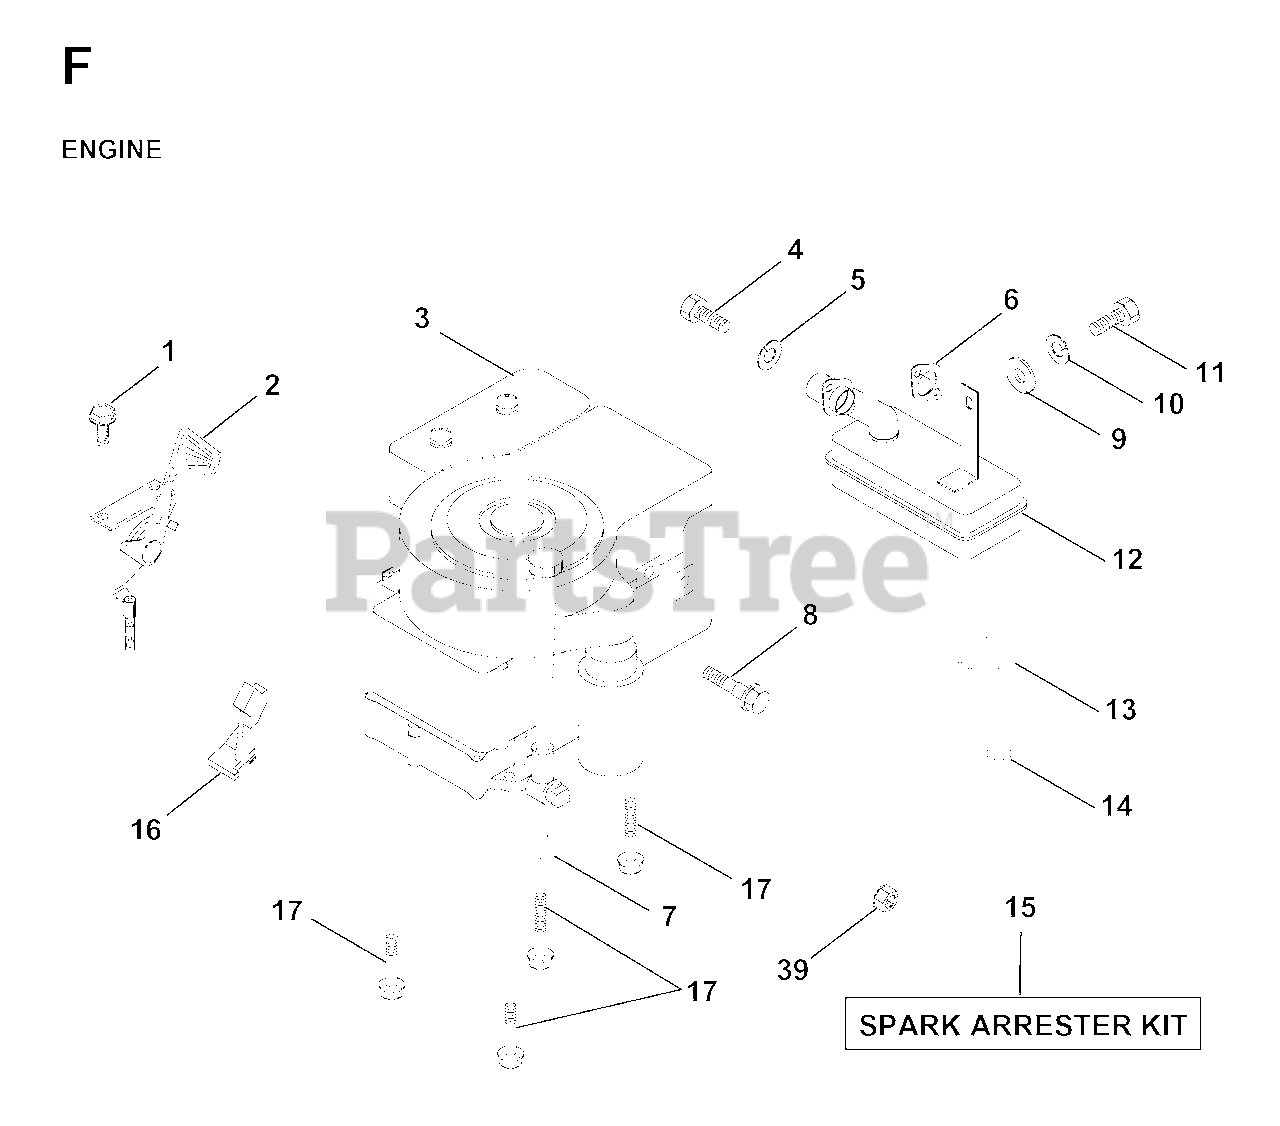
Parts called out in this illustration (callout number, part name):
2	THROTTLE CONTROL
4	SCREW
5	LOCKWASHER
6	GASKET ENG
7	LOCKWASHER
9	WASHER
10	LOCKWASHER
13	DEFL MUFFLER LTV
14	SCREW
15	ARRESTER SPARK (OPTIONAL)
16	STOP THROTTLE
17	SCREW LT
39	NUT FLANGE 1/4-20 STARTER NUT
